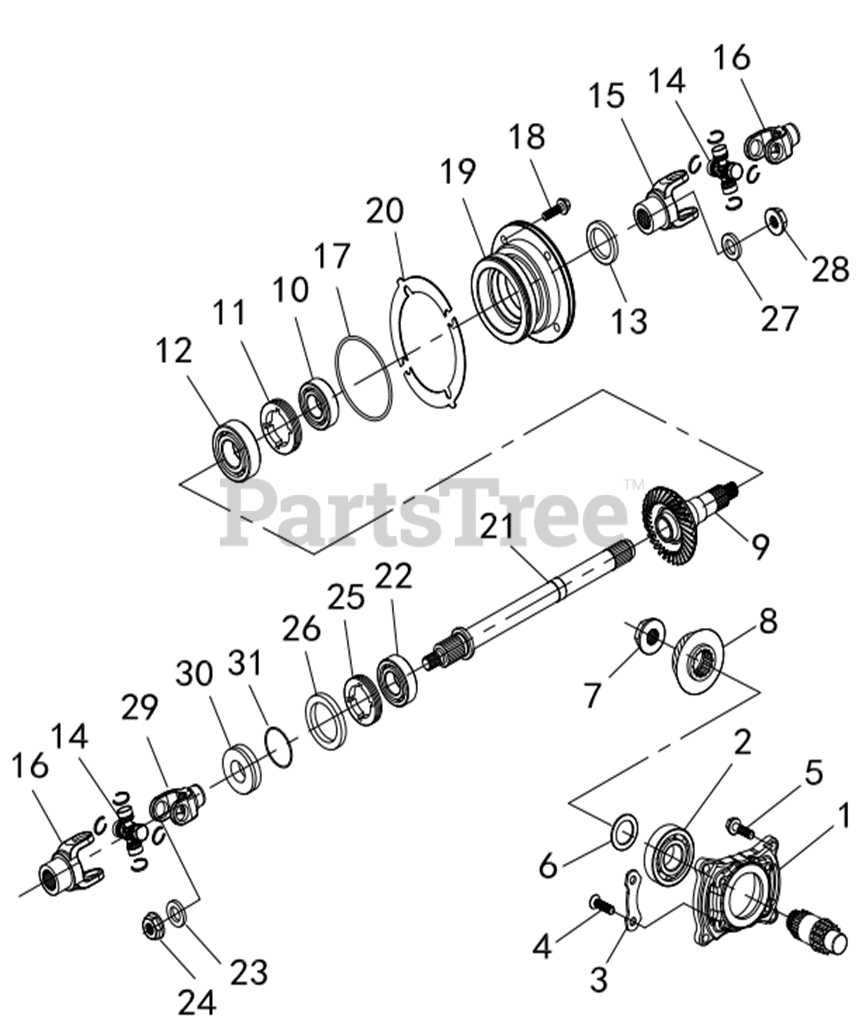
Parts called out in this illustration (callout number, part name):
1	HELICAL GEAR RETAINING BEARING
2	BEARING 6305
3	X SHAFT BEARING BLOCK PRESS PLATE
4	CROSS RECESSED COUNTERSUNK SCREW
5	HEX FLANGE BOLTS M8X30
6	SPACER 26X38X0.4
7	HEX FLANGE NUT M22X1
8	BEVEL GEAR
9	DRIVEN BEVEL GEAR
10	BEARING 63/22
11	EXTERNAL THREAD NUT M60X1.5
12	BEARING 6207
13	OIL SEAL 30X46X8
15	U-JOINT YOKE (FRONT)
16	U-JOINT YOKE (SPLINED)
17	O-RING 88X2.8
18	HEX HEAD BOLT & PLAIN WASHER
19	Y SHAFT BEARING BLOCK
20	SPACER 0.1,BEVEL GEAR
20	BEVEL GEAR SPACER KIT (2PCS -01105)
20	SPACER 0.3,BEVEL GEAR
20	BEVEL GEAR SPACER KIT (4PCS -01105)
20	SPACER 0.5,BEVEL GEAR
20	SPACER 0.6,BEVEL GEAR
21	DRIVE SHAFT
22	BEARING 6205
23	WASHER 14.5X32X5
24	SELF-LOCKING NUT M14X1.5
25	EXTERNAL THREAD NUT M55
26	OIL SEAL 44X60X7
27	WASHER 16.5X28X4
28	SELF-LOCKING NUT M16X1.5
29	U-JOINT YOKE (REAR)
30	SHAFT BUSHING 25x44x15
31	O-RING 25x2.4
